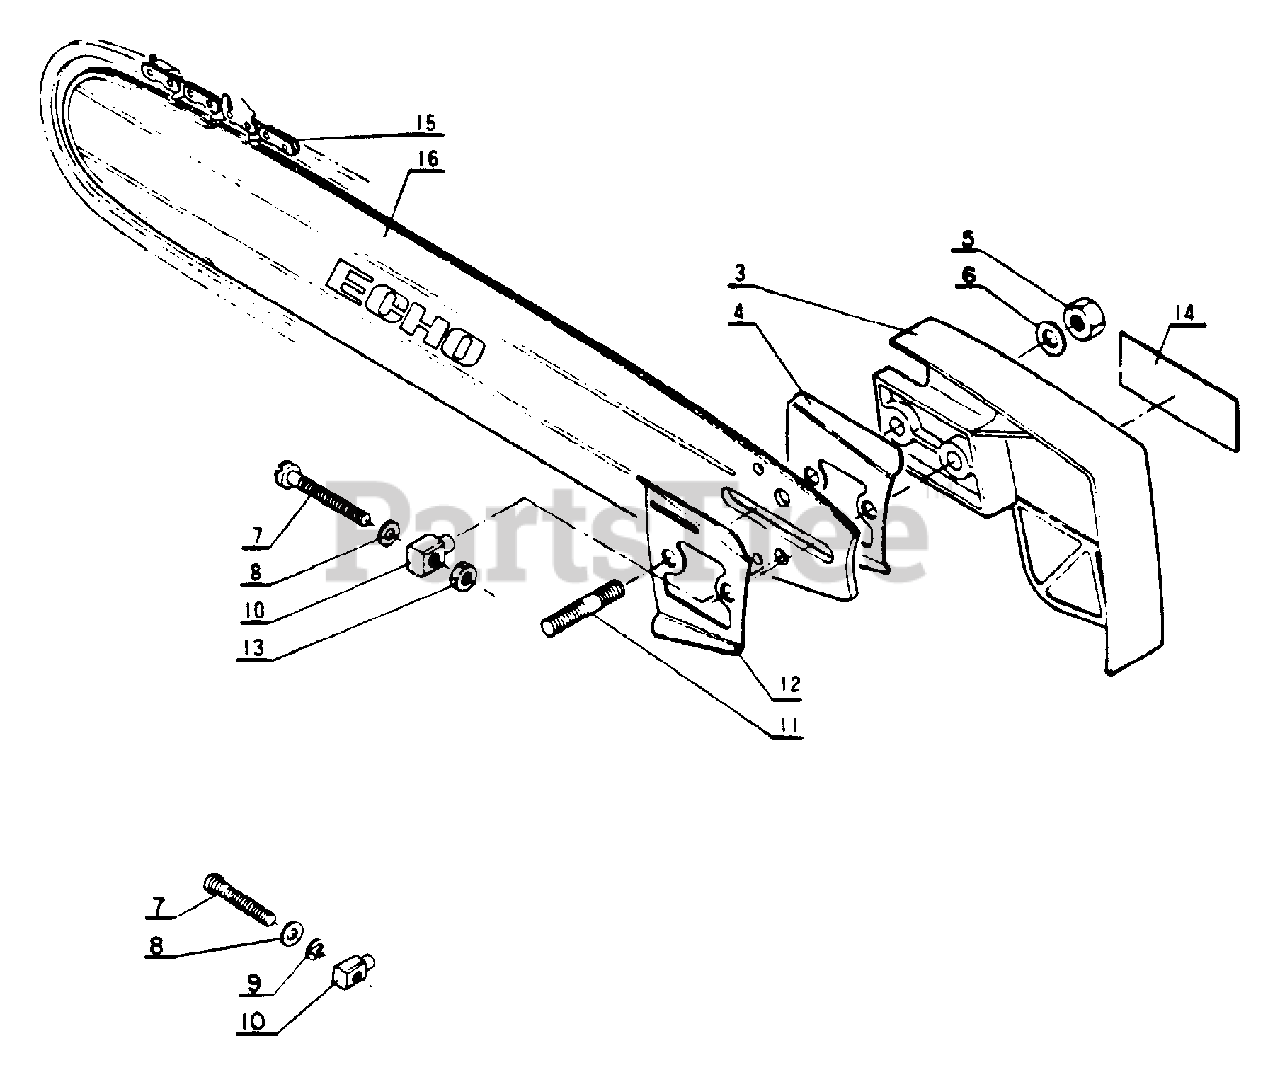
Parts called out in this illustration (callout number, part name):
3	GUARD, SPROCKET
4	PLATE, GUIDE - OUTER
5	NUT - FLANGE
6	WASHER 8.5×16×1.2
7	SCREW, ADJUSTER
8	WASHER
9	RING, RETAINING
10	TENSIONER
10	TENSIONER, CHAIN
11	STUD, GUIDE BAR
12	PLATE, GUIDE - INNER
13	LOCKNUT - 6
13	LOCKNUT - 5
14	LABEL - ECHO
16	GUIDE BAR
